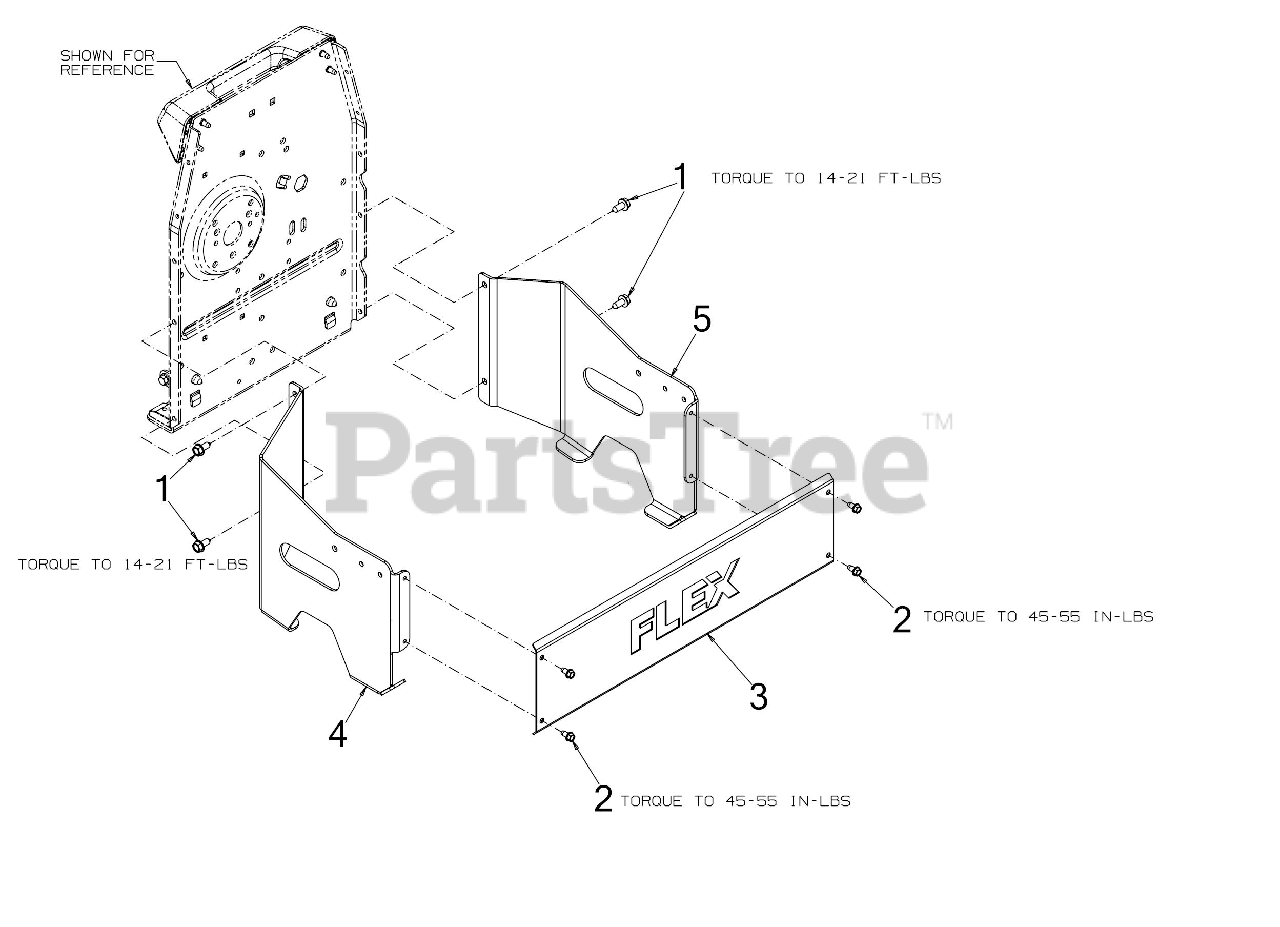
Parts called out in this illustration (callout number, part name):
1	SCREW 5/16-18 x .750
2	SCREW 1/4-20 X.500
4	RIGHT HAND FRAME BRACKET
5	LEFT HAND FRAME BRACKET
